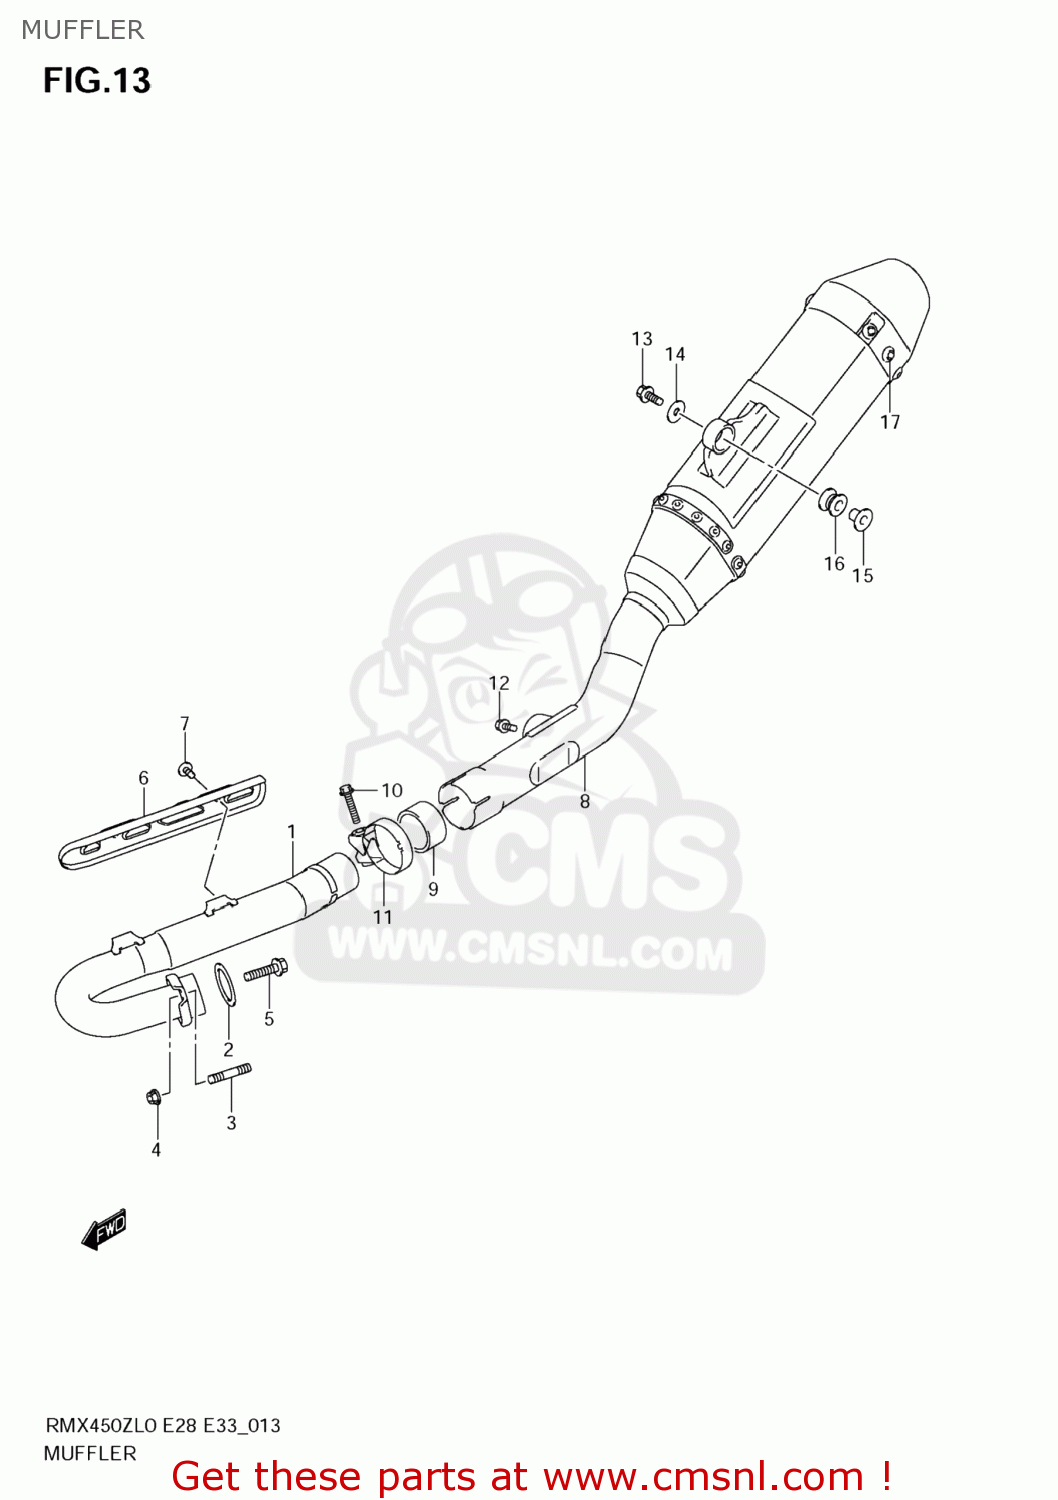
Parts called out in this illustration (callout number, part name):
1	PIPE,EXHAUST
2	GASKET,EXHAUST PIPE (NAS)
3	BOLT,STUD
4	NUT
5	BOLT(8X25)
6	COVER,EXHAUST PIPE
7	BOLT(6X8)
8	BODY,MUFFLER
9	CONNECTOR,MUFFLER
10	BOLT(8X35)
11	CLAMP,CONNECTOR
12	BOLT(8X20)
13	BOLT(8X35)
14	WASHER(8.5X26X1.6)
15	SPACER(8.6X12X17.5)
16	CUSHION
17	SCREW(6X13)
